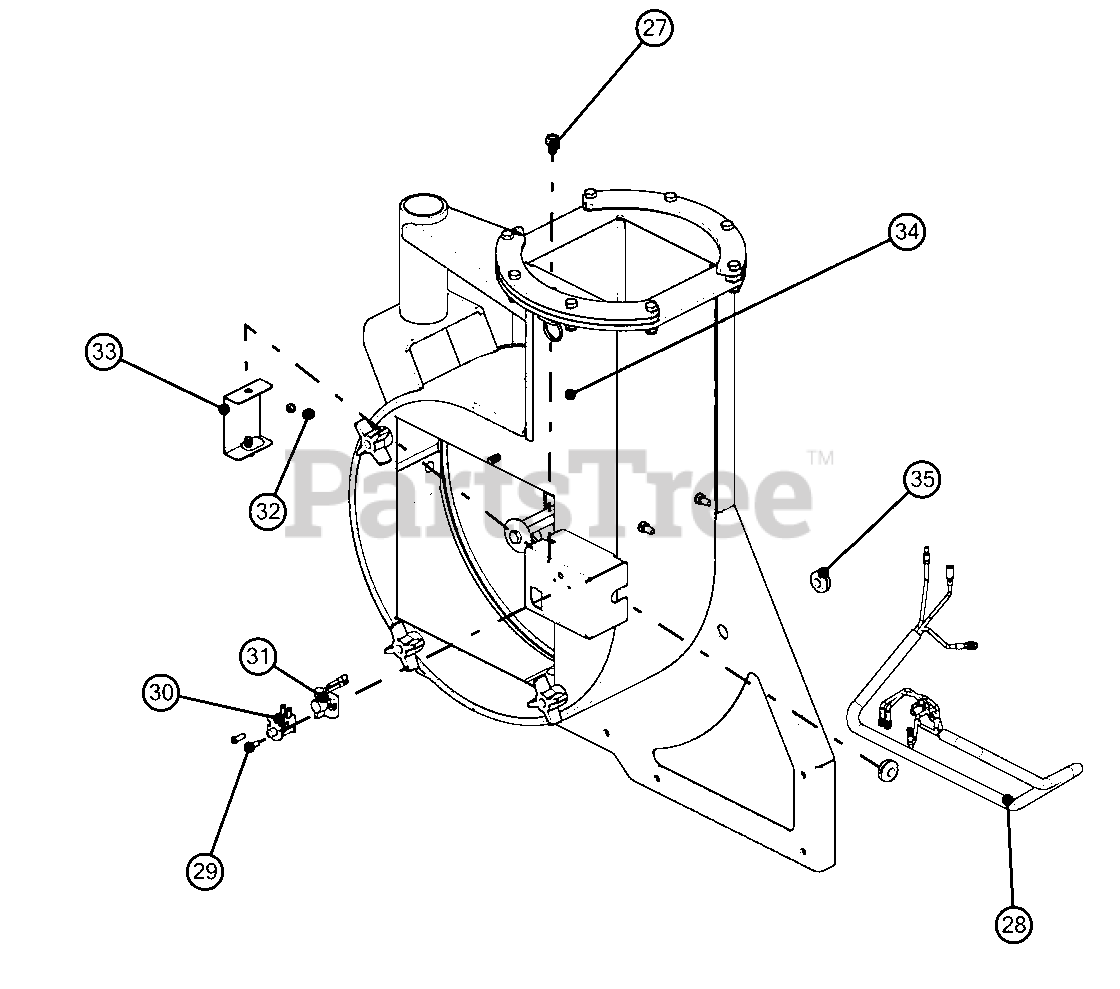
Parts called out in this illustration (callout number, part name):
27	BOLT, 5/16-18X.625 FGH 5
28	WIRE HARNESS, 14HP TL
29	SCR-MC 8-32 X .62 NICKEL
30	SWITCH- SNAP MTG N.C.
31	ENGINE SWITCH
32	NUT-LK-NYL 8-32 W/INSTR YWZC
33	WLDT, SWITCH COVER
34	WLDT, BLOWER 14 TRUCK LOADER
35	GROMMET, ROUND RUBBER .625X.19
